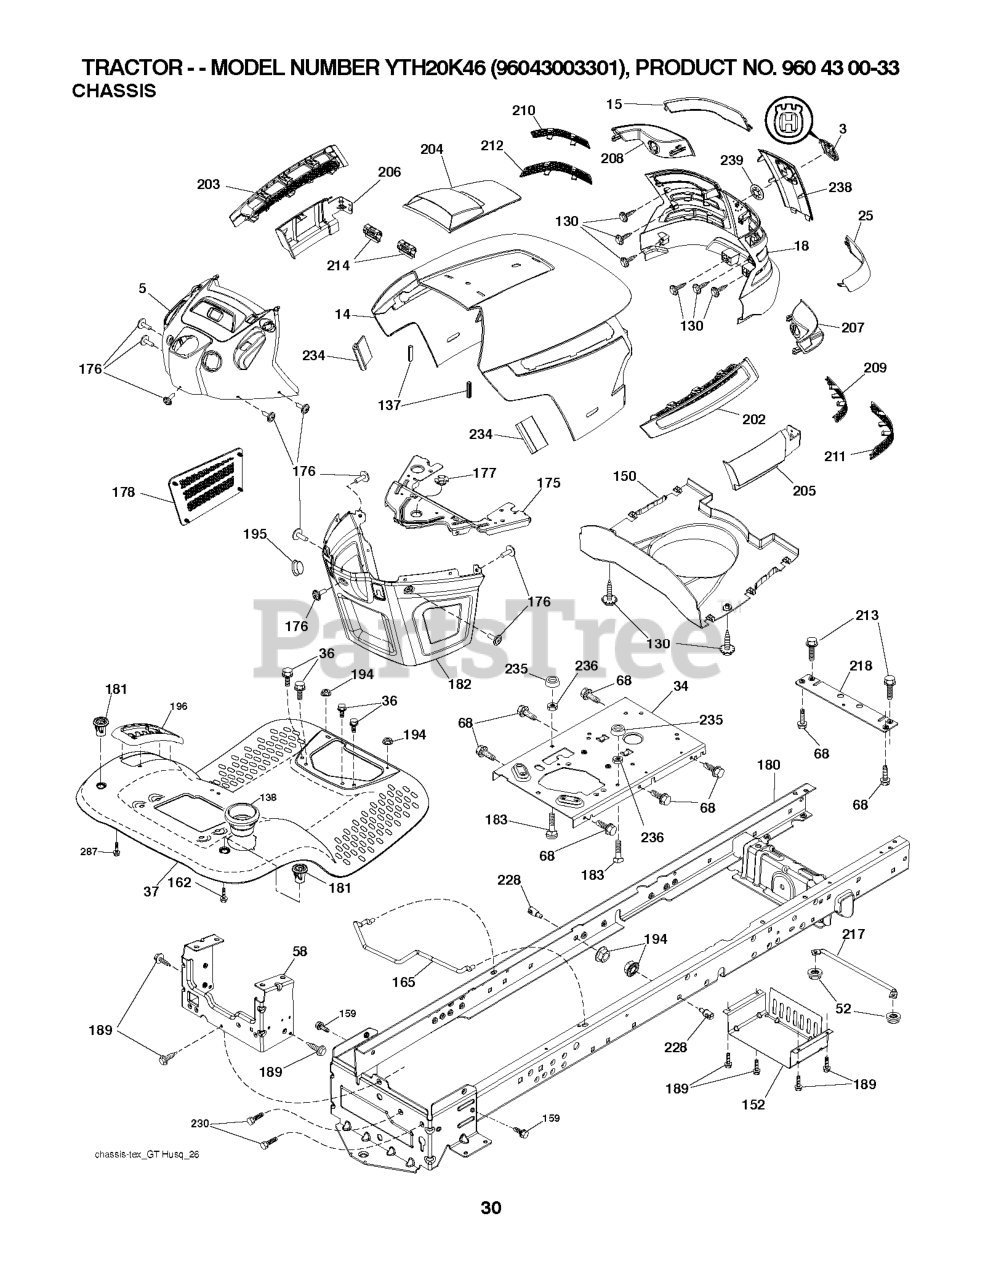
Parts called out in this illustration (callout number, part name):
3	RP LOGO
14	HOOD
15	LENS.LH.TEX.GT.HUSQ.CL
18	GRILL.ASM.HUSQ.TG/CRD.W/TRIM
25	LENS.RH.TEX.GT.HUSQ.CL
34	PLATE.ENGINE.WELDED.CHASSIS
36	SCREW 5/16"
37	FENDER
52	LOCKNUT
58	DRAWBAR UPPER 2PC SMALL FENDER
68	Screw 5/16-18 x 1/2 Hex, Self Tapping 5/16-18 x 1/2
130	SCREW.#10 X 0.750.BOS
137	BUMPER DASH
138	CUPHOLDER.TL.TEX.418
150	AIR.DUCT.TEXGT.HUSQ.SV
152	SHIELD.BROWNING.W/TEX
159	SCREW, 3/8-16X3/4
162	SCREW.HI-LO.CONSOLE
175	PLATE.CROSSMEMBER.HUSQ
176	SCREW.#10-24X5/8.RN.QU
177	BUSHING, STEERING
178	CARGO.ASM.NET.TXGT.W/C
180	CHASS.WLDMNT.TL.12GA/2P.48/54
181	BUSHING.MNT.FEND.CRGO.
182	DASH.LOWER.COMMON.12V.ADAPTOR
183	BOLT.5/16-18X1-1/4 FULL.THREAD
189	SCREW
194	NUT LOCK HEX FLANGE 5/16-18
195	PLUG.HOLE.DASH.LOWER.12V.BLK
196	CONSOLE.DECK.LIFT.TLT.GR
202	VENT.SIDE.HOOD.HUSQ.RH.GREY
203	VENT.SIDE.HOOD.HUSQ.LH.GRAY
204	HOOD VENT
205	SKIRT.HOOD.SIDE.HUSQ.RH.GREY
206	SKIRT.HOOD.SIDE.HUSQ.LH.GREY
207	BEZEL.RH.TEX.GT.HUSQ
208	BEZEL.LH.TEX.GT.HUSQ
209	INSERT.HEX.GRILL.HUSQ.GREY
210	INSERT.HEX.GRILL.HUSQ.
211	INSERT.HEX.GRILL.HUSQ.
212	INSERT.HEX.GRILL.HUSQ.
213	BOLT
214	CLIP.RETAINER.TINNER.
217	ROD.PIVOT.HOOD
218	X-PIECE.HOOD.STOP.NON/
228	STUD.FASTNER.W/ANTI-ROTATE
230	SHOULDER BOLT 5/16-18TT
234	BUMPER.HOOD.TEX.HUSQVARNA
235	SPACER FENDER
236	NUT.CENTERLOCK.5/16-
238	TRIM.HUSQ.TG/CRD.SERVICE
239	NUT PUSH M
287	SCREW 1/4X20
